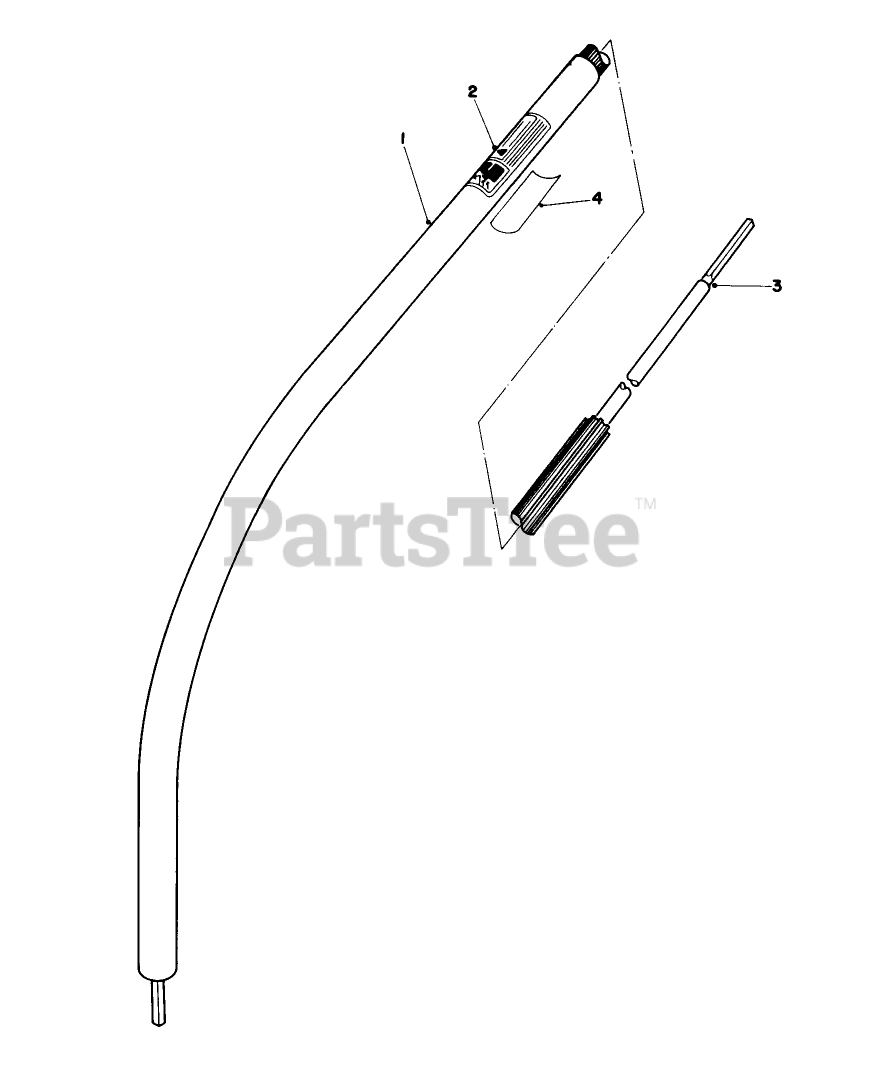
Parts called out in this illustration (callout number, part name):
1	Tube-Lower Shaft Housing (Incl. Ref. #2)
2	Decal Warning
3	Shaft-Flex
4	REP. SERIAL PLT
